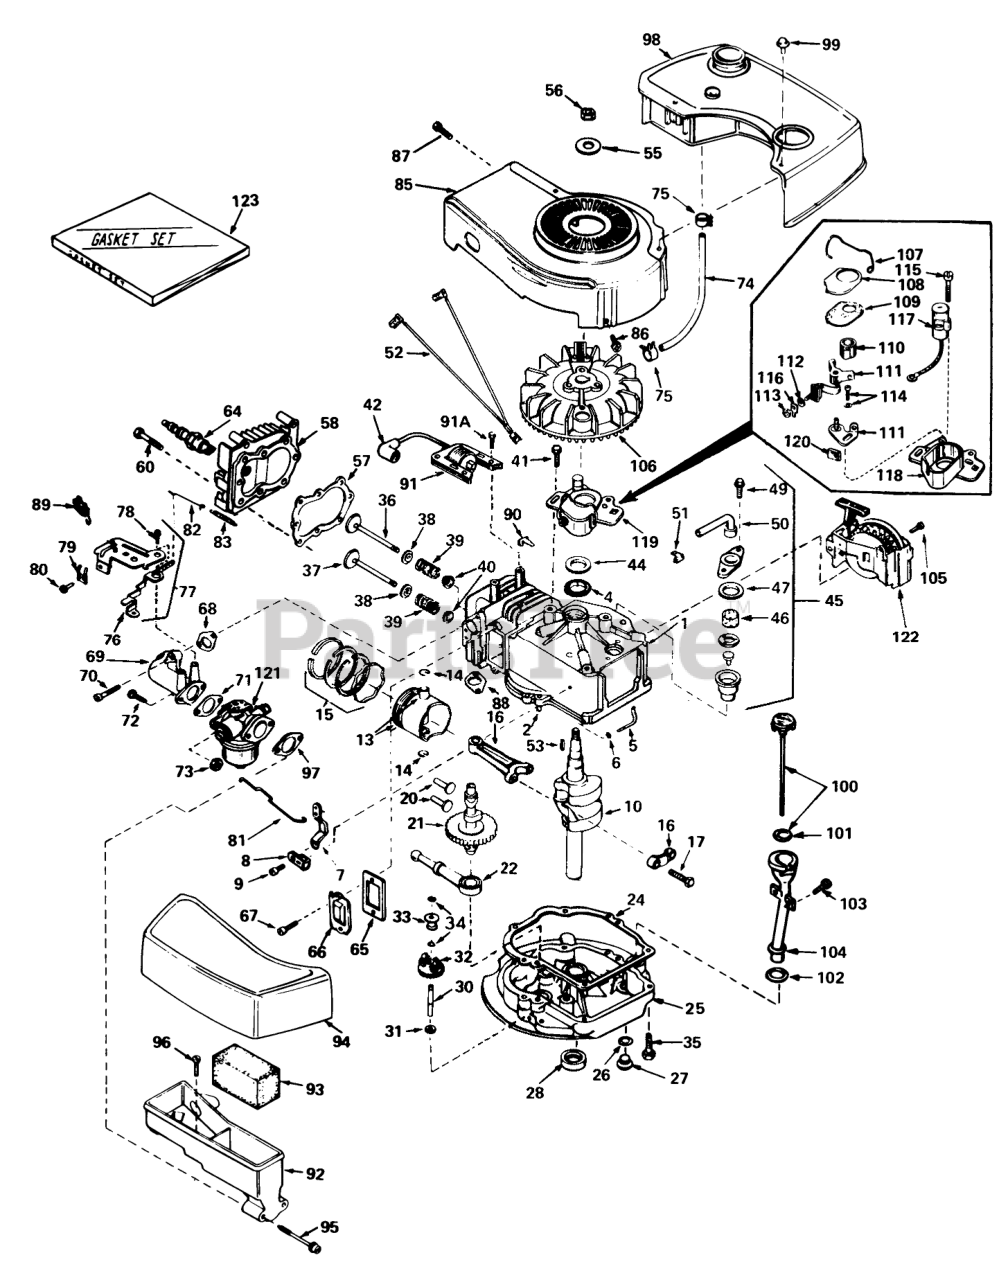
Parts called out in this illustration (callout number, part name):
1	Cylinder Assy. (Incl. Ref. #2, 4 & 105)
2	Pin-Dowel
4	Seal-Oil
5	Rod, Governor (Incl. Ref. #6)
6	Washer-Flat
7	Governor Lever
8	Clamp-Lever, Governor
9	Screw
10	Crankshaft
13	Piston & Pin Assy. (Std.)(Incl. Ref. #14)
13	Piston, Pin & Ring Assy. (Std.)(Incl. Ref. #14 & 15)
13	Piston & Pin Assy. (.010 oversize)(Incl. Ref. #14)
13	Piston, Pin & Ring Assy. (.010 oversize)(Incl. Ref. #14 &-15)
13	Piston & Pin Assy. (.020 oversize)(Incl. Ref. #14)
13	Piston, Pin & Ring Assy. (.020 oversize) (Incl. Ref. #14 & 15)
14	Ring-Retaining, Piston Pin
15	Ring Set Piston (Std.)
15	Ring Set Piston (.010 Oversize)
15	Ring Set Piston (.020 Oversize)
16	Rod Assy., Conn. (Incl. Ref. #17)
17	Bolt-Rod, Connecting
20	Lifter-Valve
21	Camshaft(Mech.Comp. Release)
22	Oil Pump ASM
24	Gasket, Mounting
25	Flange Assy., Mounting (Incl. Ref. #26 thru 30)
26	Gasket-Oil Drain
27	Plug Oil Drain
28	Seal Oil
30	Shaft-Governor
31	Washer-Flat
32	Gear Assy ., Governor (Incl. Ref. #31)
33	Spool-Governor
34	Ring-Retaining
35	Screw (1/4-20 x 1-1/4)
36	Valve, Intake (Std.)(Incl. Ref. #38, 39 & 40)
36	Valve, Intake (1/32" oversize)(Incl. Ref. #38, 39 & 40)
37	Valve, Exhaust (Std.) (Incl. Ref. #38, 39 & 40)
37	Valve, Exhaust (1/32" oversize)(Incl. Ref. #38, 39 & 40)
38	Cap-Upper Valve Spring
39	Spring-Valve
40	Cap-Valve, Spring
42	Cover-Spark Plug
44	Gasket Stator
45	Breather Assy. (Incl. Ref. #46, 47, 49, 50 & 51)
46	Element-Breather
47	Gasket-Breather
49	Screw, Hex Hd. w/Conical
50	Tube, Breaker
51	Clip, Breather
52	Wire Ground
53	682488 LB GRASS HI-
55	Washer-Belleville
56	Nut-Flywheel
57	63573 GIL 42 SNWTHW
58	Head-Cylinder
60	Screw (5/16-18x1-1/2)
64	Plug, Spark (J17LM or equiv.)
64	Plug, Spark (Champion RCJ-8)
65	Gasket-Breather
66	Cover-Valve
68	Gasket, Intake
69	Pipe, Intake
70	Screw (1/4-20 x 1)
71	Gasket-Carburetor
72	Screw (1/4-28 x 7/8)
73	Nut and Lock Washer (1/4-28)
74	Line-Fuel
75	Clamp-Line, Fuel
76	Lever Control
77	Control Assy., Speed (Incl. Ref. #76, 78 & 89)
78	Screw, Hex Washer Hd Shoulder Self-Tap
79	Conduit
80	Screw (10-32 x 3/8)
81	Link-Throttle
82	Link Governor Spring
83	Spring Governor
85	Housing Blower
86	Screw
87	Screw (10-24 x 9/16)
88	Gasket Exhaust
89	Terminal
90	Clip-Wire
91	Lamination
91A	Screw
92	Body Air Cleaner
93	Filer, Air
94	Cove, Air Cleaner
95	Screw Fil Hd.
96	Screw, Hex Hd.
97	Gasket-Air Cleaner
98	Tank, Fuel
99	Screw (10-32 x 35/64)
100	Dipstick, Oil (Incl. Ref.#101)(Twist Lock)
103	Screw (10-32 x 1/2)
104	Tube-Oil Fill
105	Screw (1/2-20x5/8)
106	FIywheel
107	Spring Breaker Box
108	Cover-Dust
109	Gasket-Dust Cover
110	Cam-Breaker
111	Breaker Assy.
114	Breaker Screw
115	Condenser Screw
116	Terminal, Ground
117	Condenser
118	Stator Plate
119	Stator Assy. (Incl. Ref. #107, 111 thru 118 & 120)
120	Felt,Cam Wiper
121	Carburetor (Incl. Ref. #71)
122	Starter-Sidemount
123	Gasket Set (Incl. Items Marked )
